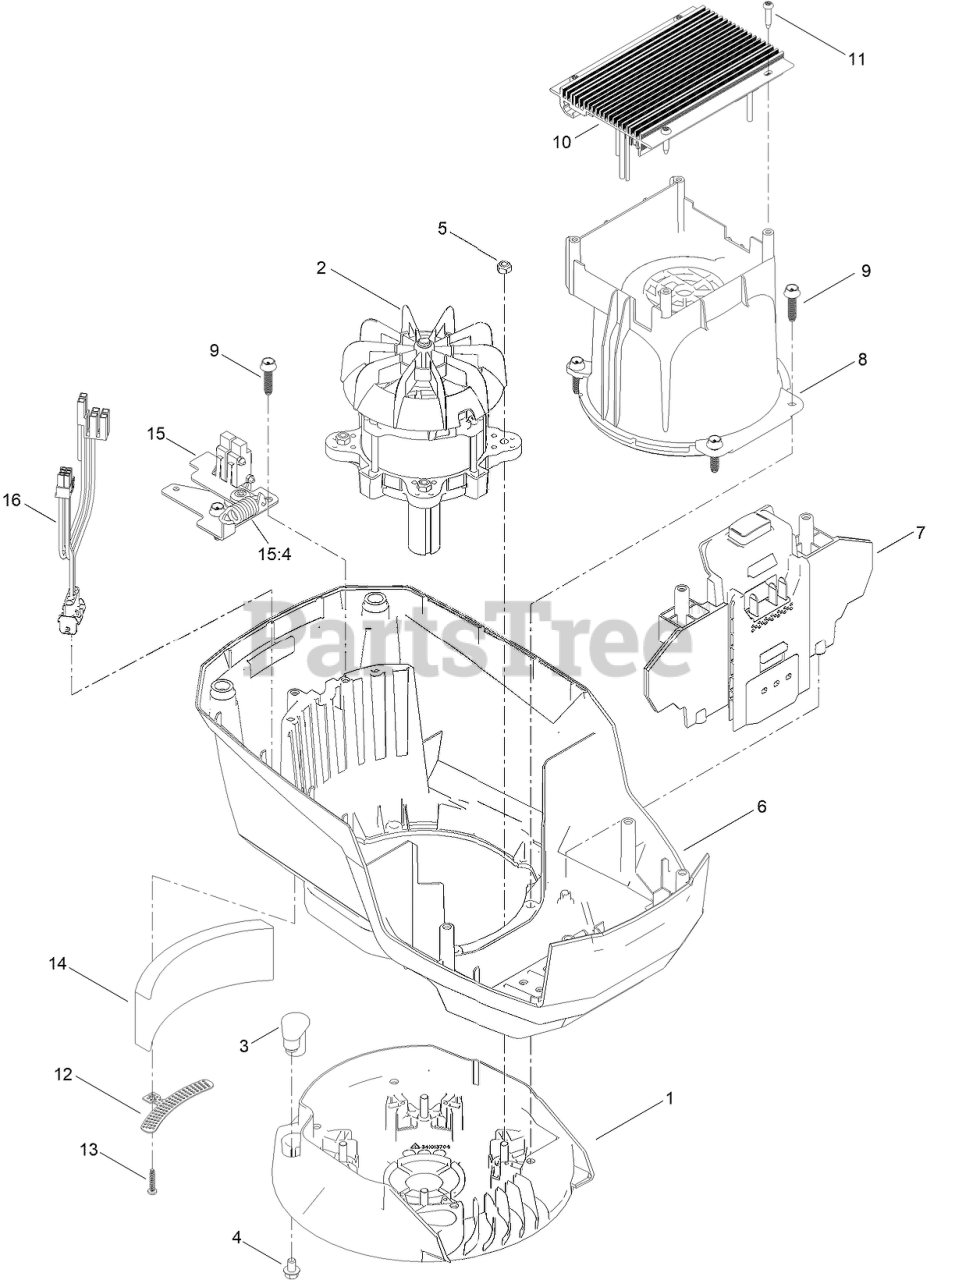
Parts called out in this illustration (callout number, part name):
1	BASE-MOUNT, MOTOR
2	MOTOR-2KW
3	INSERT-MOUNT, Motor
5	NUT-LOCK
6	SHROUD-LOWER
7	BATTERY RECIEVER ASM
8	SHROUD-MOTOR
9	SCREW-FLANGE, PLASTIC
10	DRIVER-MOTOR, 2-SPEED
12	BRACKET-FOAM
13	SCREW-PLASTIC, PPH
15	BAIL SWITCH ASM
15:4	SPRING-EXTENSION
16	HARNESS-WIRE
